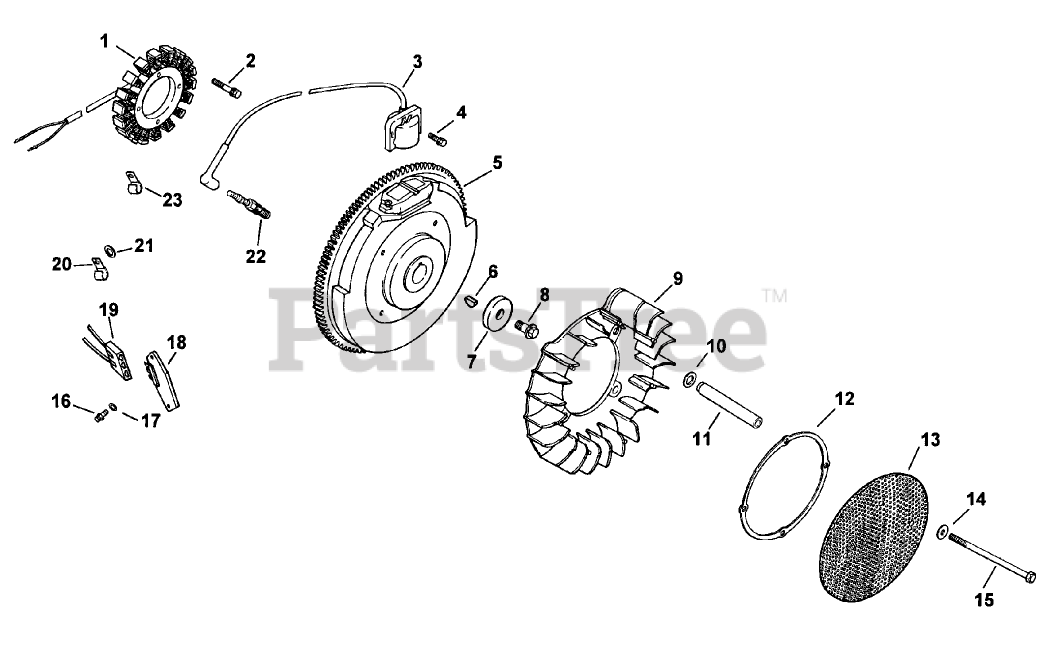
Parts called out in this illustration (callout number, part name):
1	Stator-15 amp
2	Screw
3	Module-Ignition
4	Screw
5	Flywheel
6	Key
7	Washer
8	Screw
9	Fan
10	Washer, sping
11	Spacer
12	Ring-Support
13	Screen-Grass
14	Washer
15	Screw-Hex
16	Screw
17	Washer
18	Rectifier-Regulator
19	Connector
20	Clip
21	Washer
22	Plug-Spark
23	Clip
